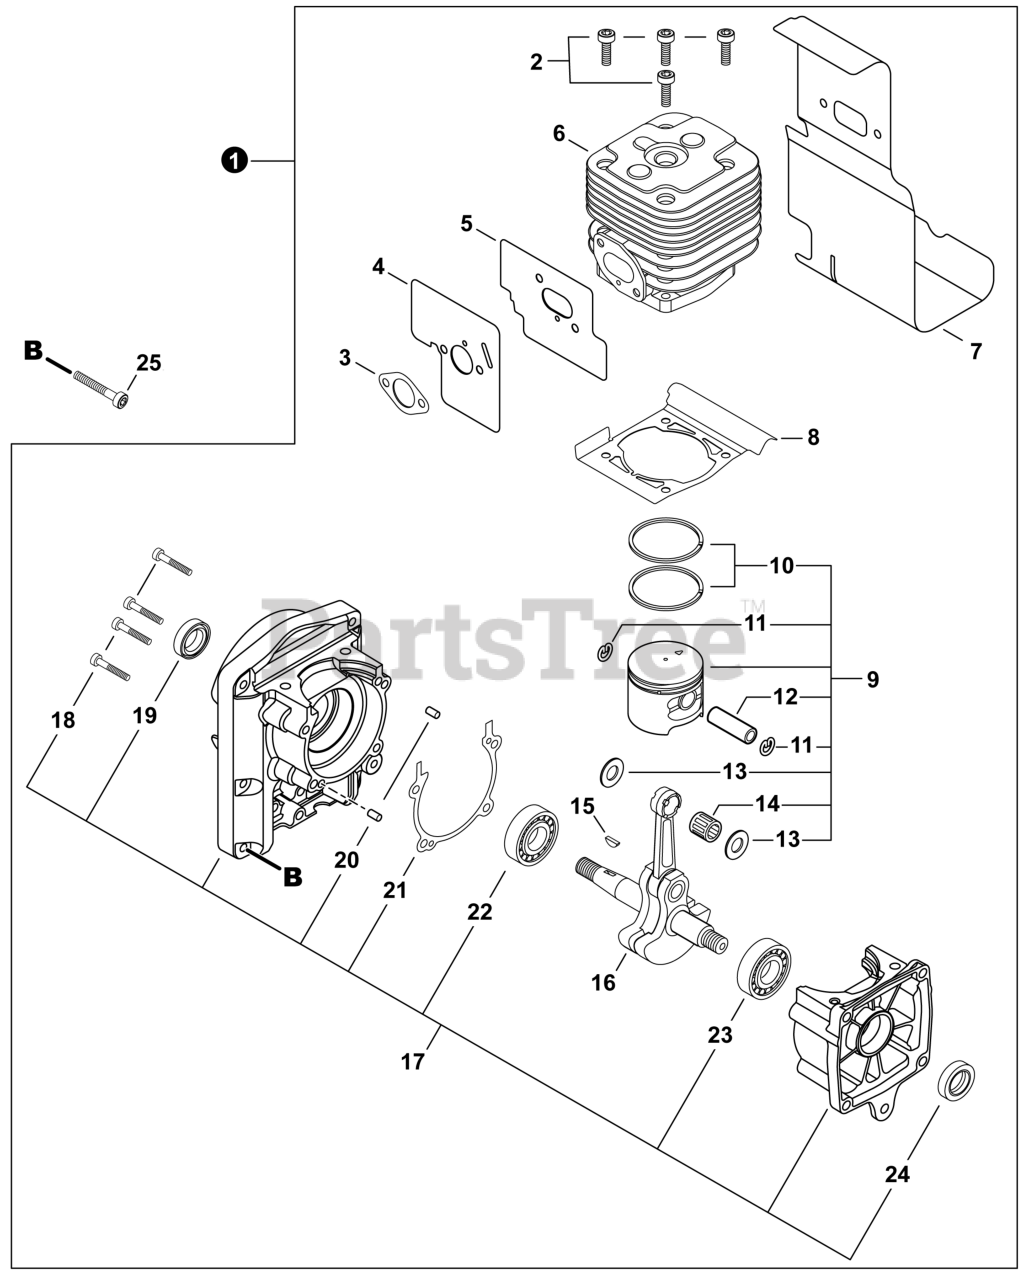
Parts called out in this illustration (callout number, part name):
1	SHORT BLOCK
2	BOLT, TORX 5x20
3	GASKET, INTAKE
4	GASKET, INTAKE
5	HEAT SHIELD, INTAKE
6	CYLINDER
7	HEAT SHIELD, EXHAUST
8	GASKET, CYLINDER
9	PISTON KIT
10	RING, PISTON
11	RING, SNAP 10
12	PIN, PISTON 10
13	WASHER, THRUST 10
14	BEARING, NEEDLE 10
15	KEY, WOODRUFF 3x14
16	CRANKSHAFT
17	CRANKCASE KIT
18	BOLT, TORX 5x30
19	SEAL, OIL 15
20	PIN, LOCATING 4x8
21	GASKET, CRANKCASE
22	BEARING, BALL 6302 C3
23	BEARING, BALL 6202
24	SEAL, OIL 15
25	BOLT, TORX 5x30
